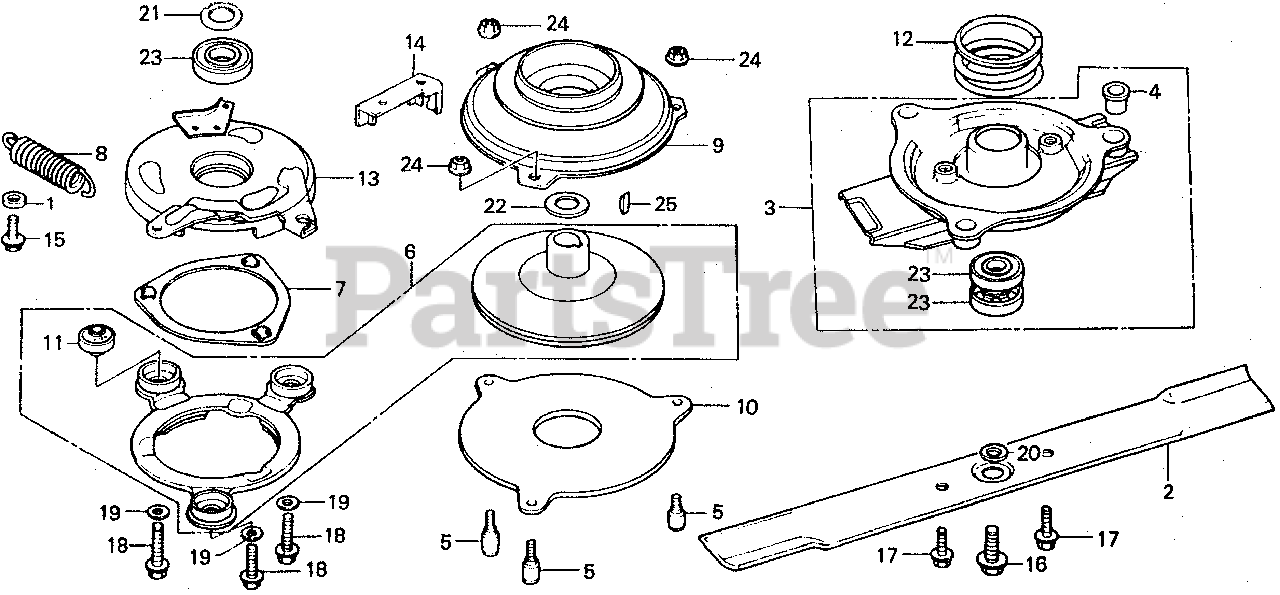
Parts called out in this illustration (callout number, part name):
1	COLLAR, FAN
2	BLADE, ROTARY
2	BLADE, ROTARY (21")
3	HOLDER ASSY., BLADE
4	BUSH, BLADE HOLDER (NOT AVAILABLE)
5	PIN, DRIVE
6	DISK SET, BRAKE & CLUTCH
7	RETAINER, BALL
8	SPRING, ROTO-STOP CLUTCH RETURN (NOT AVAILABLE)
9	PULLEY, DRIVE
10	DISK, DRIVEN
11	RUBBER, CLUTCH (NOT AVAILABLE)
12	SPRING, CLUTCH (NOT AVAILABLE)
13	PLATE, BALL CONTROL (NOT AVAILABLE)
14	PLATE, CABLE HOOK (NOT AVAILABLE)
15	BOLT, FLANGE (6X16)
16	BOLT, FLANGE UNF (3/8-24)
17	BOLT, HEX. (10X25)
18	BOLT, FLANGE (6X25) Use up to Engine SN 2056819.
19	WASHER (6MM)
20	WASHER (10MM)
21	WASHER, THRUST (22X32X3)
22	WASHER, THRUST (22X32X0.5)
23	BEARING, RADIAL BALL (60/22UU)
24	NUT, FLANGE (8MM)
25	KEY, WOODRUFF (16X15)
